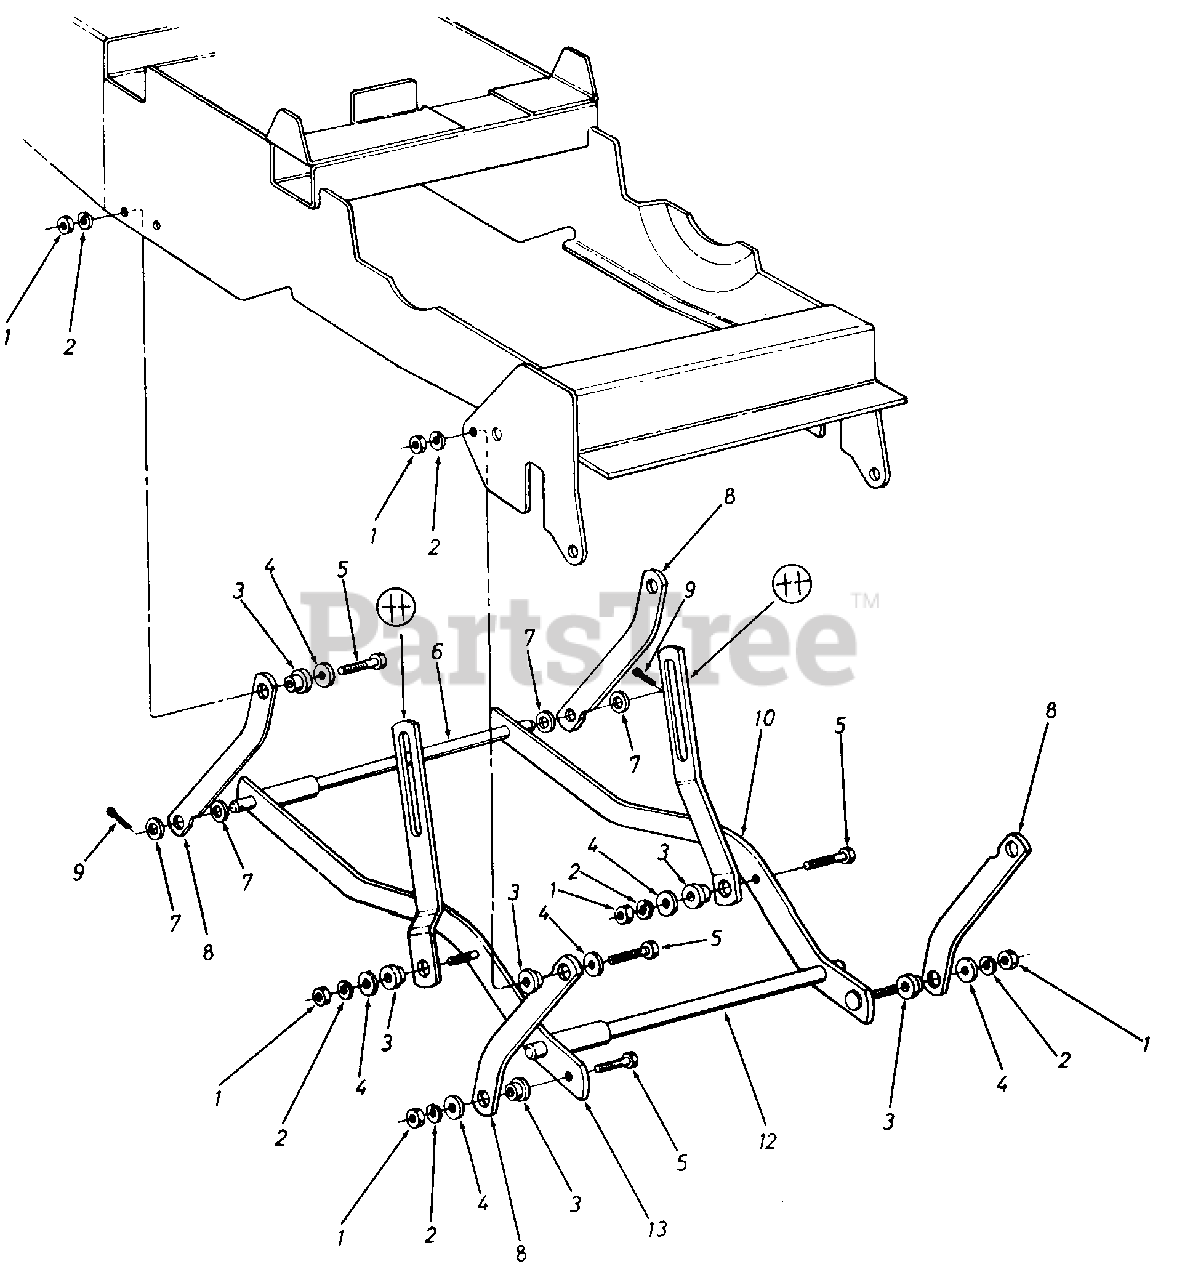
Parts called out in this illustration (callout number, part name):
1	Hex Nut 3/8-24 Thd.*
2	L.-Wash. 3/8" Scr. Heavy Duty
3	Shoulder Spacer
4	Fl.-Wash. 3/8"1.D. x 1.0" O.D.
5	Hex Scr. 3/8-24 x 1.50" Lg. Grade 5
6	Cross Shaft Ass'y.-Rear
7	Fl.-Wash. 5/8" I.D. x 1-1/8"0.D.
8	Lift Arm
9	Cotter Pin 5/32"Dia. x 1.25"Lg.
10	Lift Arm Link Ass'y.-L.H.
12	Cross Shaft Ass'y.-Front
13	Lift Arm Link Ass'y.-R.H.
